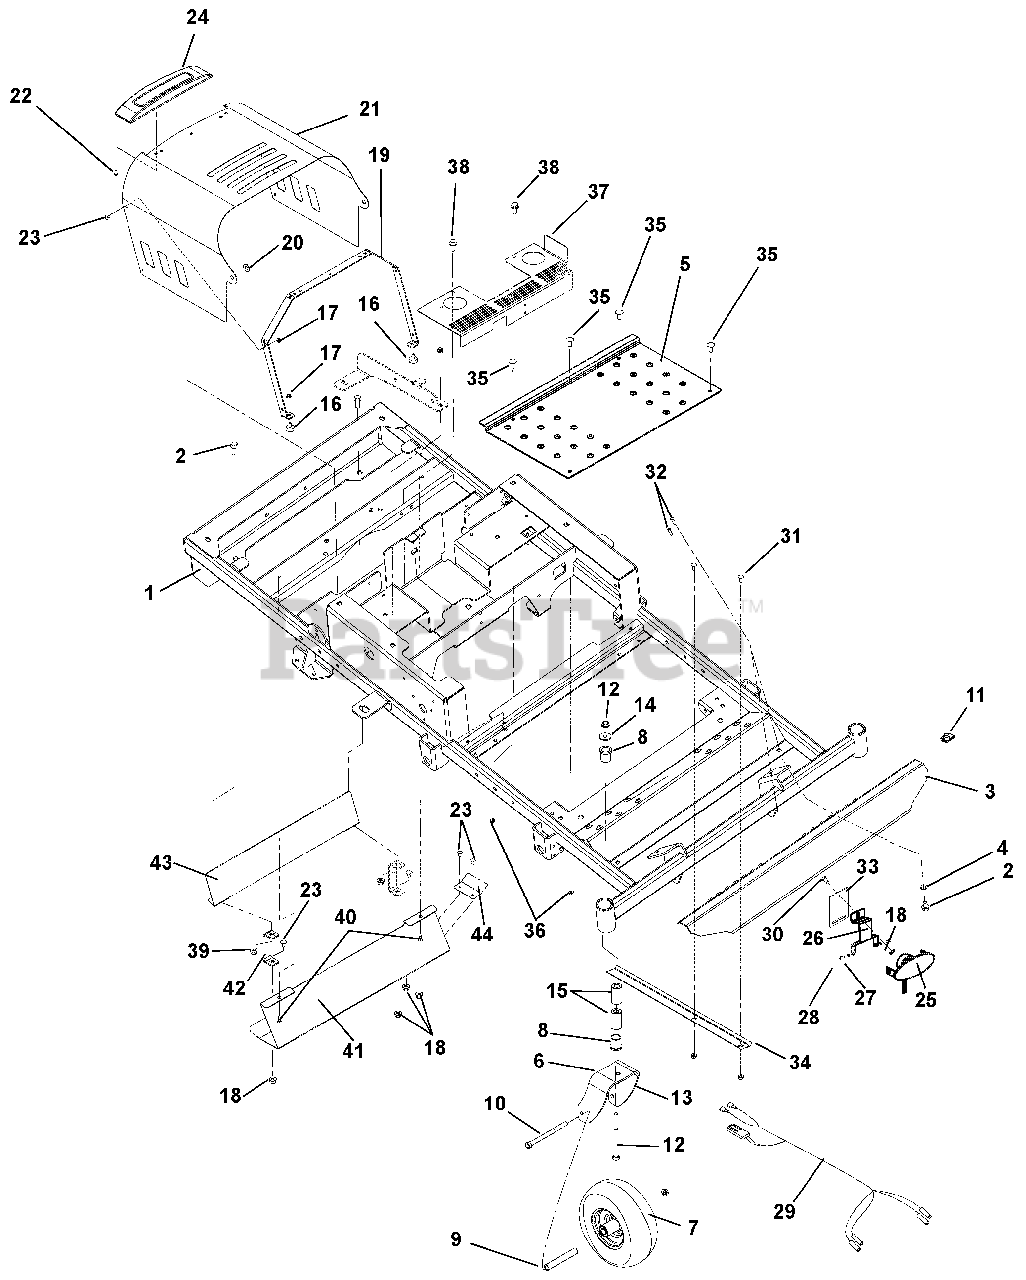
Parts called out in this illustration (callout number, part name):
1	WLDMT, FRAME ZT/ZOOMXL (2013)
2	@BLT-HEX .38-16X1.00 GR5 YWZC
3	WMT, FOOTREST
4	@WSHR-LK .38X.094 REG YWZC
5	PANEL WLDMT, FOOT PLATE
6	WMT, CASTER FORK
7	TIRE/WHEEL ASSY, 11X4-5
8	BSHG-FLG 1.00X1.25X1.50X1.50EP
9	SPACER, ROLLED WHEEL
10	@BLT-HEX .50-13X6.50 GR5 YWZC
11	NUT-RTNR .375-16X.37
12	@NUT-LK-TOP-FLG .50-13 YWZC
13	@BLT-HEX .50-13X5.00 GR5 YWZC
14	WSHR-FL-STL.511X1.441X.125 YWZ
15	SPACER, CASTER .50X1.00X1.84
16	BUMPER, RUBBER
17	@NUT-SPNLK-FLG .312-18 YWZC
18	@NUT-LK-TOP-FLG .25-20 YWZC
19	HOOD STRAP
20	WSHR-FL-NYL .518X1.000X.080
21	HOOD, XL
22	SCR-.25X.62 PN HD BOSSSCREW YZ
23	@BLT-RDHDSQNK .25-20X.50 G5YZ
24	TRIM-ZOOM XL HOOD ARIENS
25	LIGHT ASSEMBLY
26	BRKT, FOG LIGHT
27	@NUT-LK-NYL 10-24 W/INSRT YWZC
28	@SCR-MCH 10-24X.50 HWH YWZC
29	HARNESS, XL HEADLIGHT
30	@BLT-RDHDSQNK .25-20X.75 G5YZ
31	@BLT-RDHDSQNK .31-18X.75 G5YZ
32	@BLT-HEX .25-20X.75 GR5 YWZC
33	BRKT, LIGHT FRAME MOUNT
34	BRACKET, LIGHT HARNESS
35	@BLT-HEX .31-18X1.00 GR5 YWZC
36	@NUT-LK-NYL-FLG .31-18 YWZC
37	BRACKET, XL CE FAN GUARD
38	@SCR-TAP .38-16X.50 HWH TR YWZ
39	@NUT-LK-TOP-FLG .38-16 YWZC
40	SCR-TAP .25-20X.50 HWH TR YWZ
41	GUARD, MUFFLER HEAT
42	STRAP, MUFFLER GUARD
43	SHIELD, HOT SURFACE
44	DEFLECTOR, HEAT SHIELD
